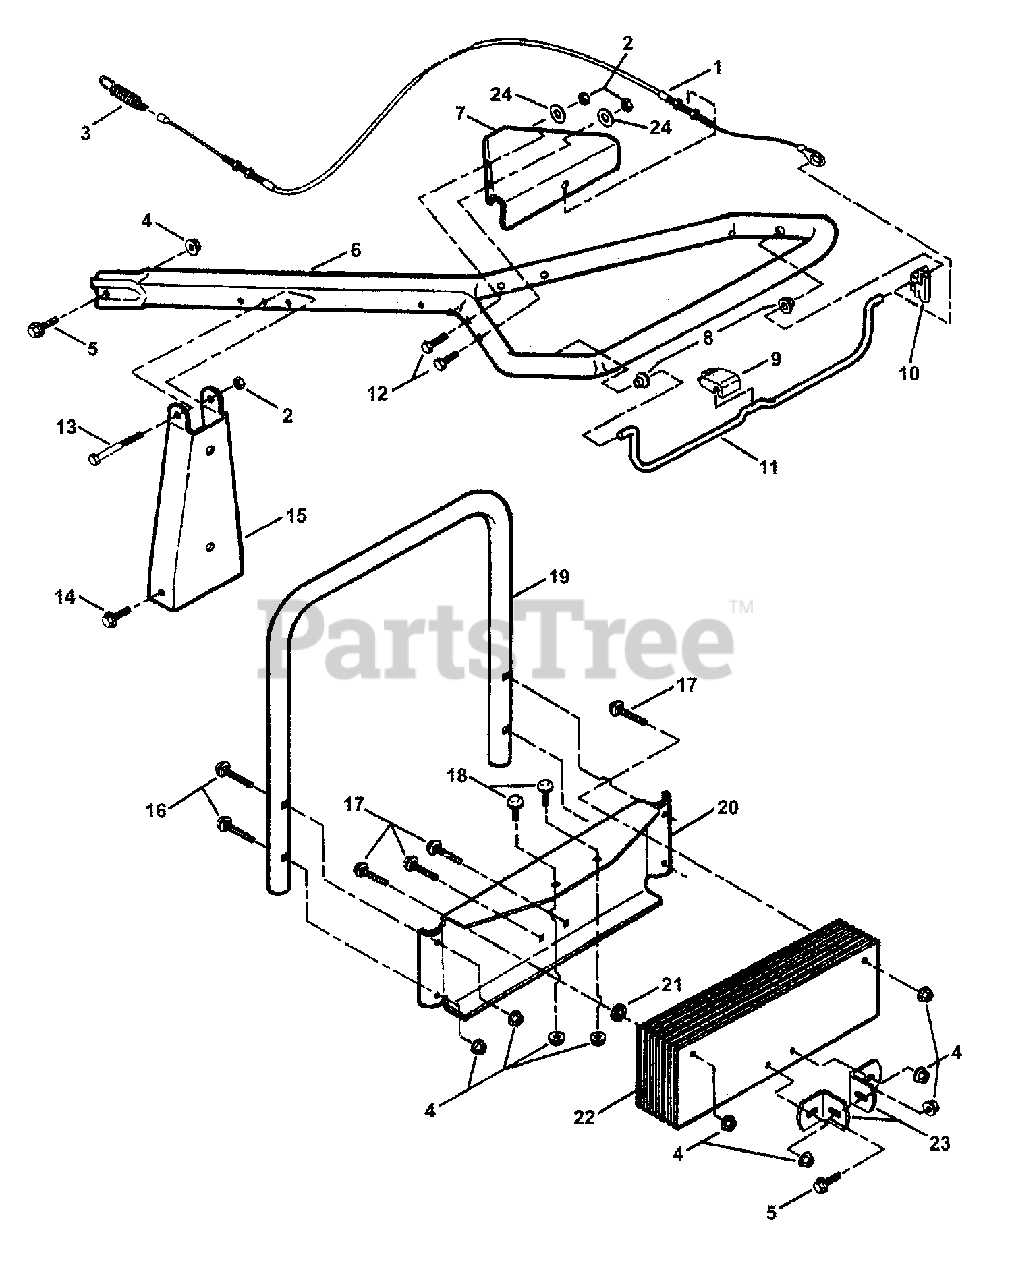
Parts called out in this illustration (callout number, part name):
1	CABLE Clutch
2	NUT, 5/16-18 Hex Center Lock
3	SPRING, Tine
4	NUT, 5/16-18 Hex Flange Lock
5	BOLT, 5/16-18 x 1" Hex Flange Lock
6	BAR, Handle IRT
7	PANEL, Tiller Dash
8	BUSHING
9	COVER, Cable
10	CATCH, Bail
12	SCREW, 5/16-18 x 1-1/2" Hex Head Cap GR5
13	SCREW, 5/16-18 x 2-3/4" Hex Head Cap GR5
14	SCREW, 5/16-18 x 5/8" Hex Washer Self-Tap
15	SUPPORT, Handle
16	BOLT, 5/16-18 x 1-1/2" Sq. Neck Carriage GR5
17	BOLT, 5/16-18 x 1-3/4" Sq. Neck Carriage GR5
18	BOLT, 5/16-18 x 3/4" Square Neck Carriage GR5
19	BAR, Stand-Up
20	BOX, Weight
21	RETAINER, 5/16" Bolt (Black)
22	WEIGHT, Steel
23	BRACKET, Weight
24	WASHER, 5/16" Flat
